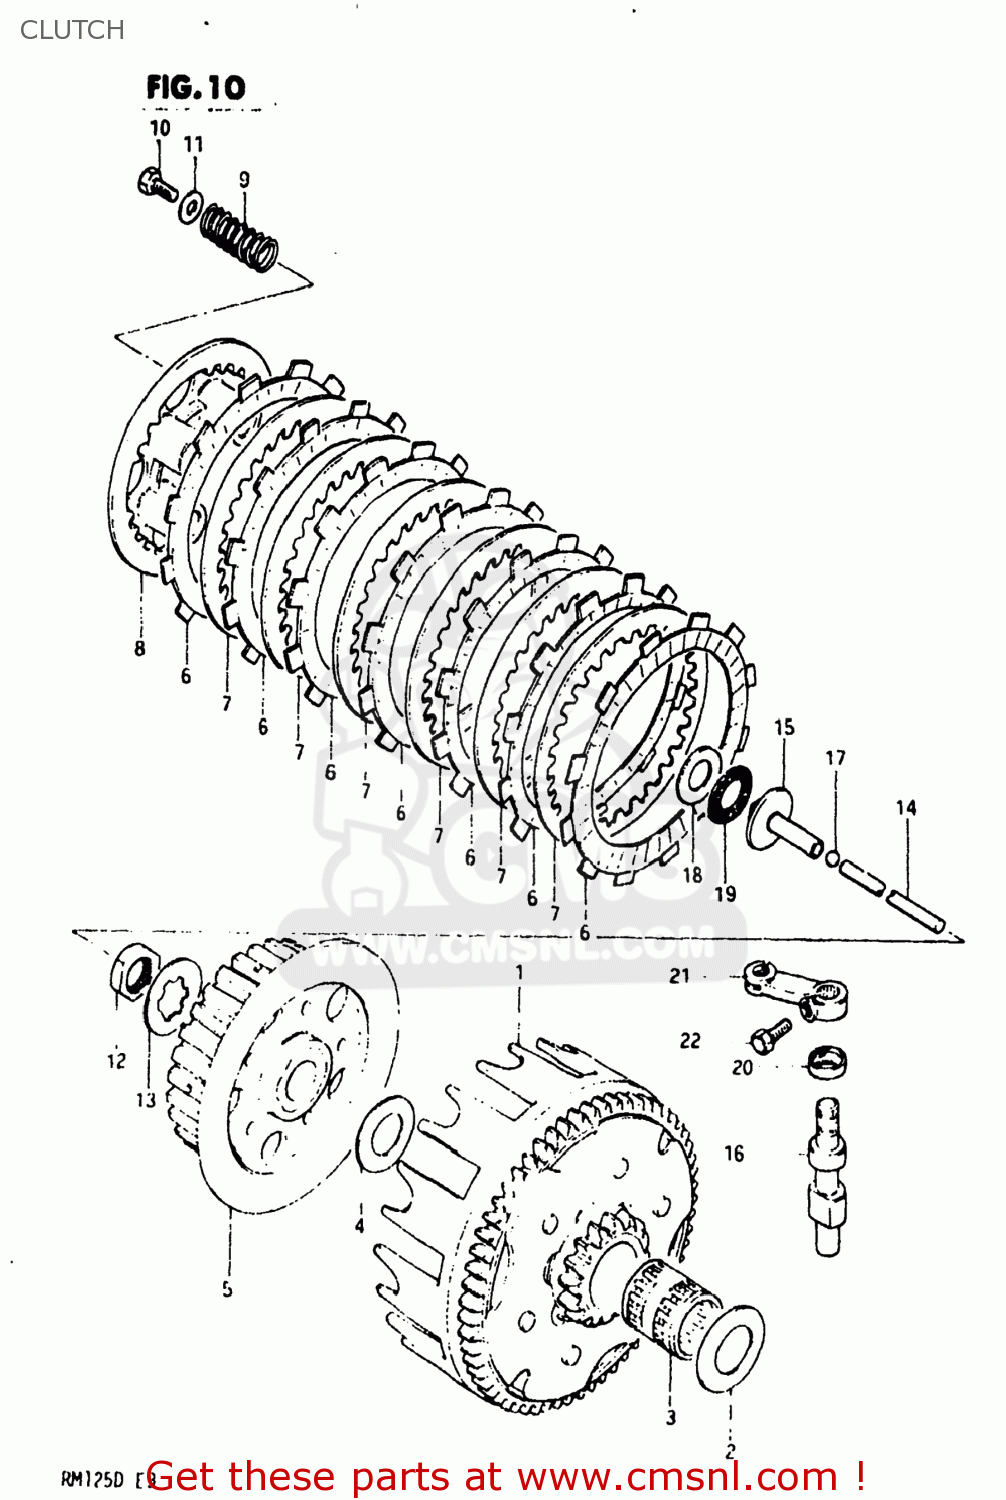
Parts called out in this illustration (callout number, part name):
1	GEAR ASSEMBLY,PRIMARY DRIVE
2	WASHER,THRUST
3	BEARING(20X25X26)
4	WASHER
5	HUB,CLUTCH SLEEVE
6	PLATE,CLUTCH DRIVE
7	PLATE,CLUTCH DRIVEN
8	PLATE,CLUTCH PRESSURE
9	SPRING
10	BOLT(5X16)
11	WASHER (5.5X16X1.2)
12	NUT
13	WASHER,LOCK
14	ROD,CLUTCH PUSH
15	PIECE,CLUTCH PUSH
16	CAMSHAFT,CLUTCH RELEASE
17	BALL
18	WASHER
19	BEARING(15X28X2)
20	OIL SEAL
21	ARM,CLUTCH RELEASE
22	BOLT, UPPER
